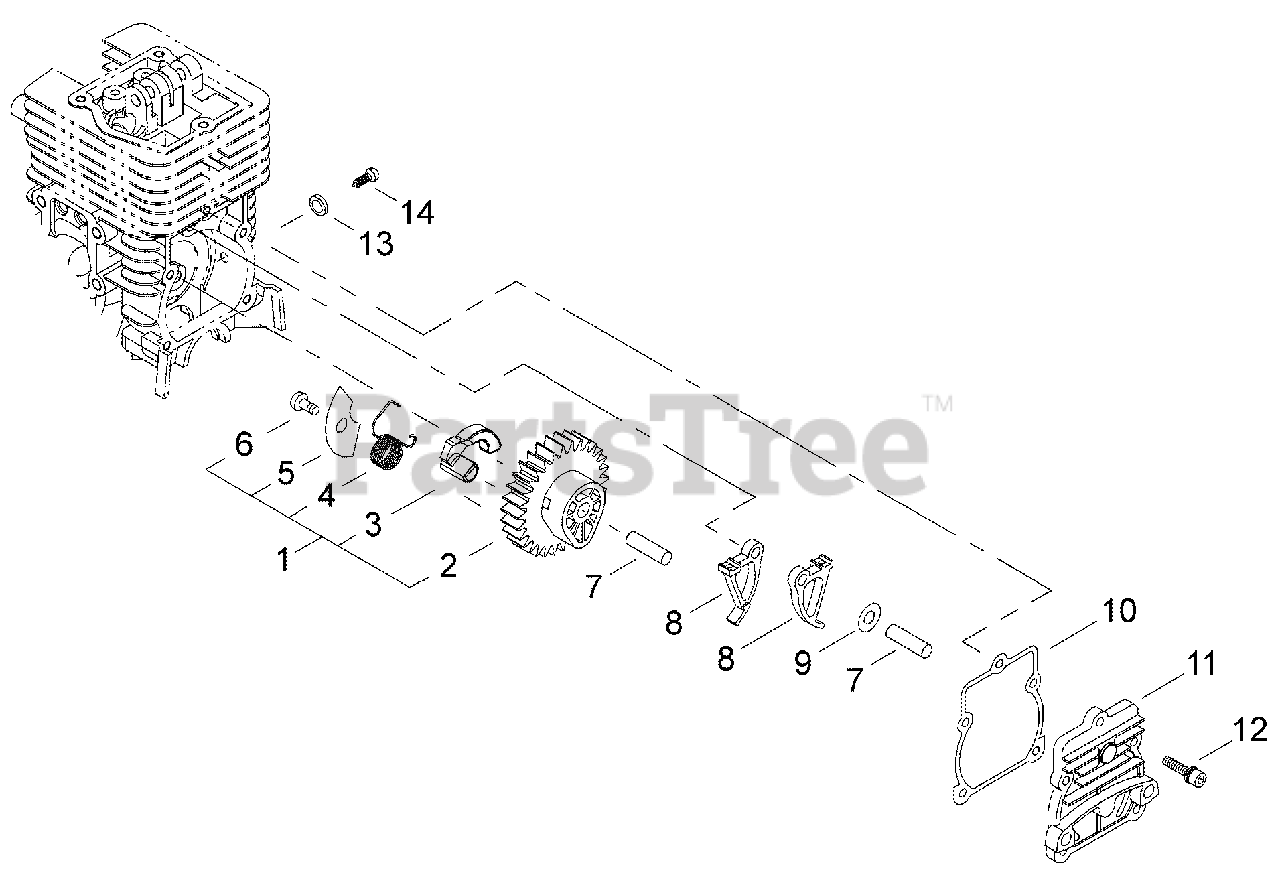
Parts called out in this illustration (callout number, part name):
1	CAM GEAR ASSY
2	GEAR, CAM
3	WEIGHT
4	SPRING
5	COVER, PLATE
6	SCREW - 4X6 -- TAPPING
7	PIN - LOCATING
8	FOLLOWER, CAM
9	WASHER - 5
10	GASKET
11	COVER, CAM GEAR
12	SCREW - 4X14
13	WASHER
14	SCREW - 5
